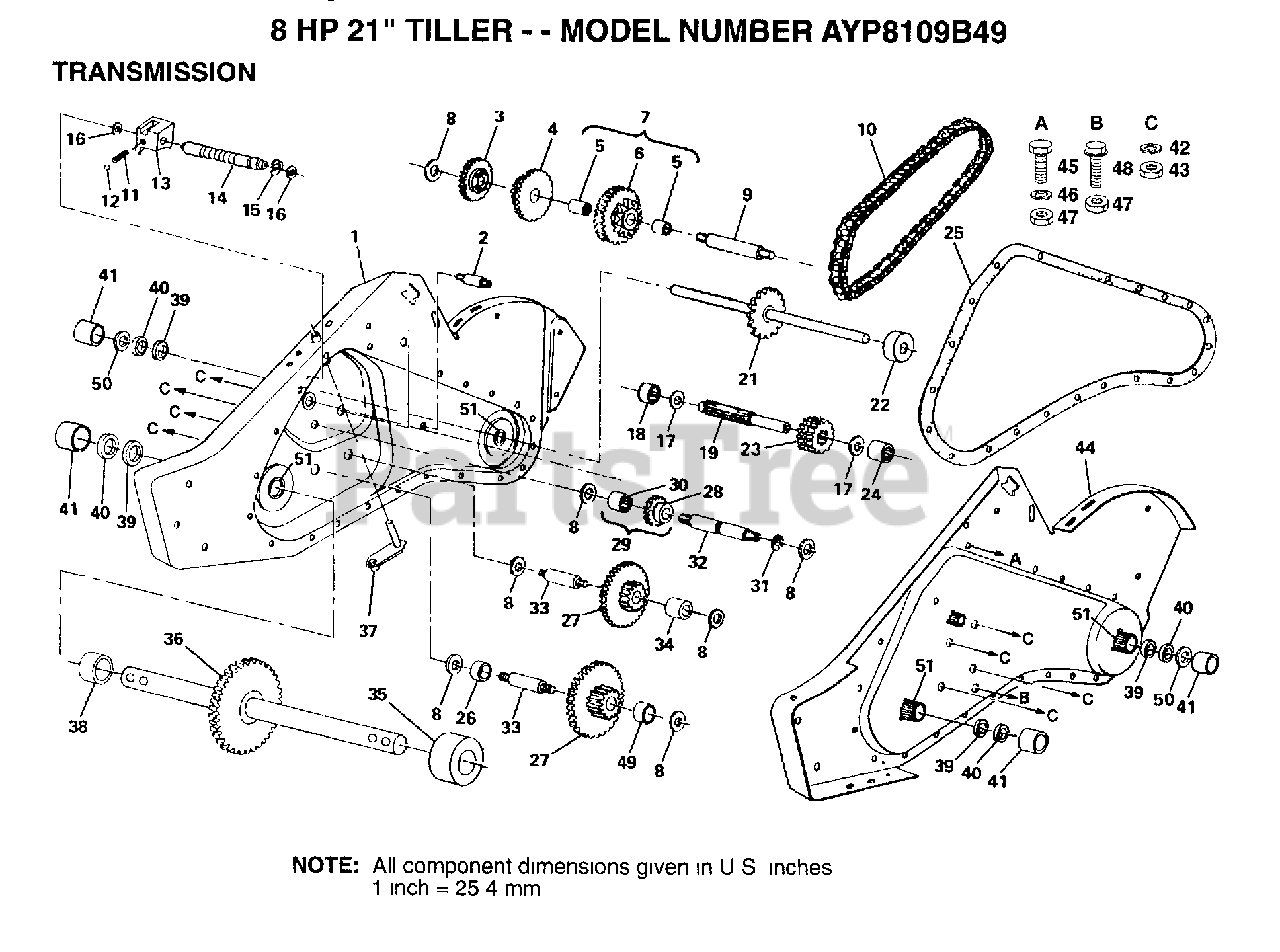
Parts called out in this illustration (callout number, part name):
2	BOLT TI
3	REVERSE GEAR TI
4	CLUSTER GEAR TI
5	"CRT, BEARING"
7	SPROCKET ASSY TI
8	WASHER
9	REDUCTION SHFT TI
10	CHAIN TI
11	SPRING-SHIFT CRT
13	SHIFT FORK TI
14	SHIFT SHAFT TI
15	KLIP RING
17	"T, BEARING"
18	"TI, BEARING"
19	SHAFT INPUT T
21	SHAFT TINE CRT
22	SPACER CRT
23	INPUT PINION TI
24	NEEDLE BRNG LT
25	GEARCASE GSKT TI
26	SPACER CRT
27	GEAR CLUSTER CRT
28	REVERSE GEAR TI
29	GEAR ASSY TI
30	NEEDLE BEARING TI
31	KLIP RING
32	REVERSE SHAFT TI
33	SHAFT CRT
34	SPACER CRT
35	SPACER CRT
36	SHAFT ASSY CRT
37	BRACKET ASM SHIFT
38	SPACER CRT
39	OIL SEAL STD
40	SEAL RING RUBBER
41	CUP.FORMED.
42	LOCKWASHER
43	NUT.ASF.HEX.7/16
45	BOLT
46	LOCKWASHER
47	NUT.HEX.5/16-18
48	BOLT TI
49	SPACER CRT
50	RING SPIRAL CRT
